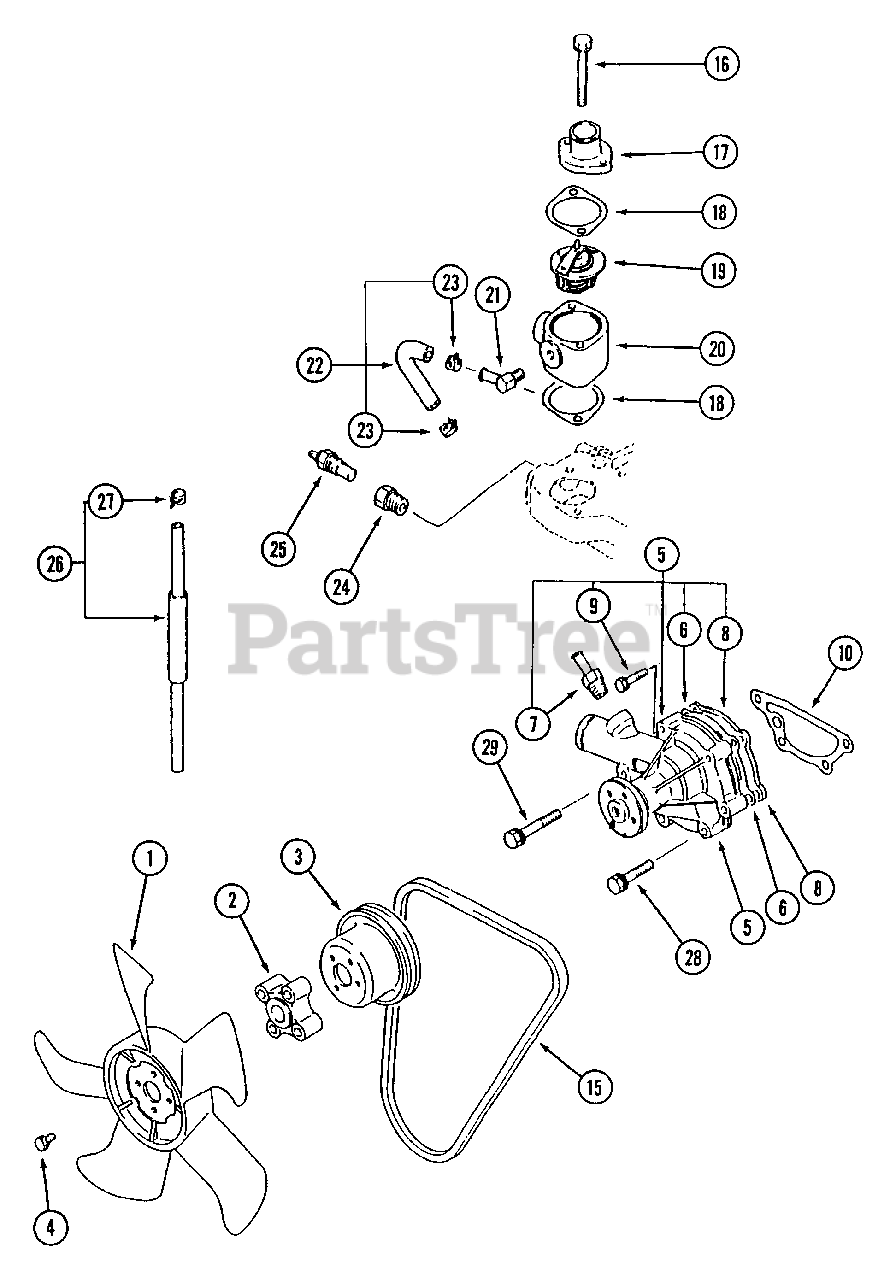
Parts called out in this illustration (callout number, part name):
1	Fan, Cooling
2	Spacer, Fan
3	Pulley, Water Pump
4	Bolt,
5	Pump Ass'y., Water
6	Gasket, Water Pump
7	Joint, Water Pump
8	Plate, Water Pump
9	Bolt,
10	Gasket, Water Pump
16	Bolt,
17	Fitting, Water Outlet
18	Gasket
19	Thermostat
20	Fitting, Thermostat
21	Joint, Water Hose
22	Hose Ass'y., Water Bypass
24	Joint, Gauge Unit
25	Gauge Unit, Water Temp
26	Hose Ass'y., Water Drain
28	Bolt, Washer Ass'y.
29	Bolt, Washer Ass'y.
